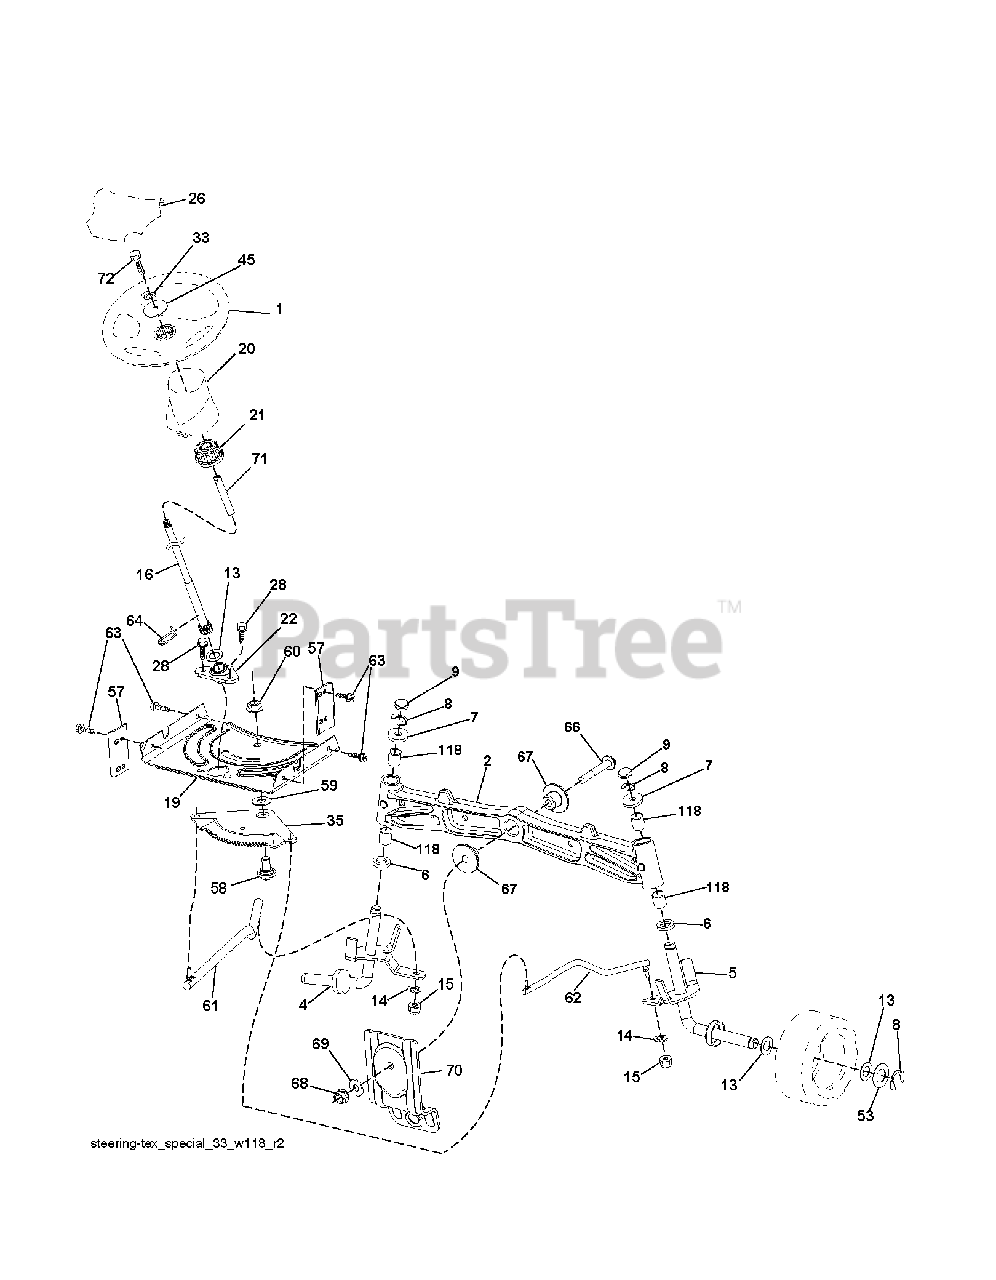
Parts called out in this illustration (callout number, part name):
1	WHEEL.STEER.HUSQ.SR.498.OVMLD
2	AXLE.SVC.ASM CAST IRON.TEX
4	SPINDLE.WELDED.LH.15"TEX
5	SPINDLE.WELDED.RH.15"T
6	THRUST WASHER
9	CAP.SPINDLE.BLACK
14	WASHER, LOCK 3/8
15	NUT CROWNLOCK 3/8-24
16	SHAFT.STEER.3/4.PLATED.TEX
19	PLATE.STEER.DDL.NLT/NG
20	STEERING.BOOT.HUSQ.LT
21	ADAPTER, WHEEL STNG..
22	STEERING.SUPT.LOWER.
26	INSERT.CAP.WHL.STRG.HUSQ.PREM
28	SCREW, 3/8-16X3/4
33	LOCKWASHER
35	GEAR.SECTOR.PLATE.DDL.
45	WASHER.11/32
53	WASHER.HARDENED
57	BRACKET.UPSTOP.TEX
58	BOLT.SHOULDER.SECTOR.P
59	WASHER.THURST.SECTOR.S
60	NUT FLANGE LOCK 5/8-11
61	DRAGLINK.LH.BALLSTUD.D
62	DRAGLINK.RH.BALLSTUD.D
63	SCREW
64	RETAINER.CLIP.SPRING.S
66	BOLT HEX FGHD 7/16-14 X 3 SERR
67	BUSHING.PM.FRONT AXLE
68	NUT.LOCK.FLANGE.7/16
69	WASHER.1.5X.505X.118
70	BRKT.DECK.SUSPENSION.F
71	SHAFT.EXTEN.STRG.SPLINE
72	BOLT 5/16-18 X 4 W/PATCH
118	BUSHING, AXLE CAST
